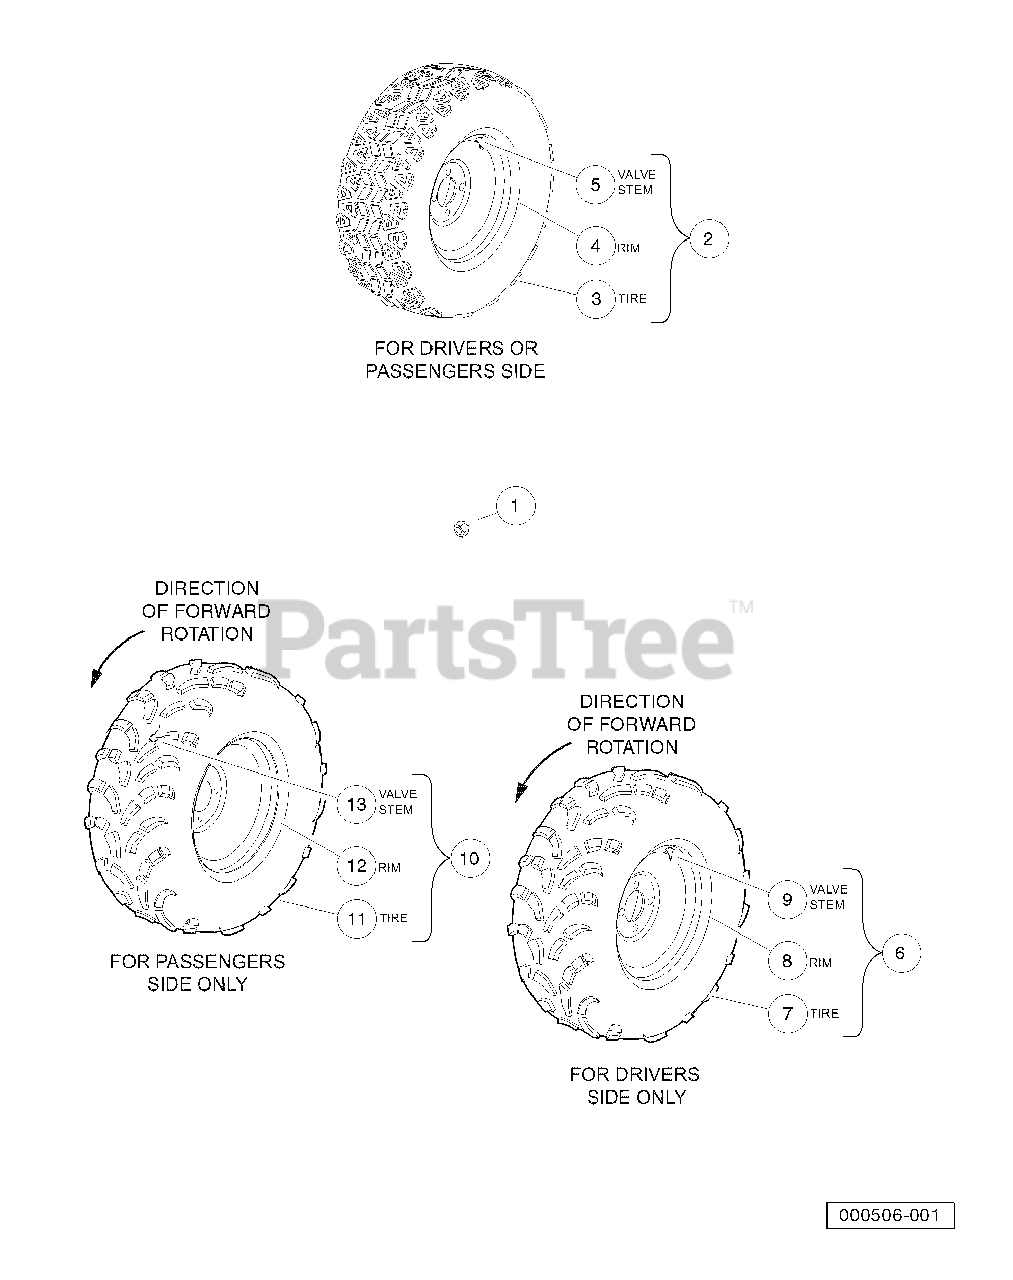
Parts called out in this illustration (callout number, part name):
1	Nut, Lug, 1/2-20 SAE J2283
2	Black Tire Asm HDAT 10.5 In
3	Heavy Duty All Terrain Tire, 25"
4	Wheel, All trail, 10 Win, Black
5	Valve Stem
6	Black Tire Asm Mud 11.0 In Left-Hand
7	Mud Tire, 25"
8	Wheel, All trail, 10 Win, Black
9	Valve Stem
10	Black Tire Asm Mud 11.0 In Right-Hand
11	Mud Tire, 25"
12	Wheel, All trail, 10 Win, Black
13	Valve Stem
